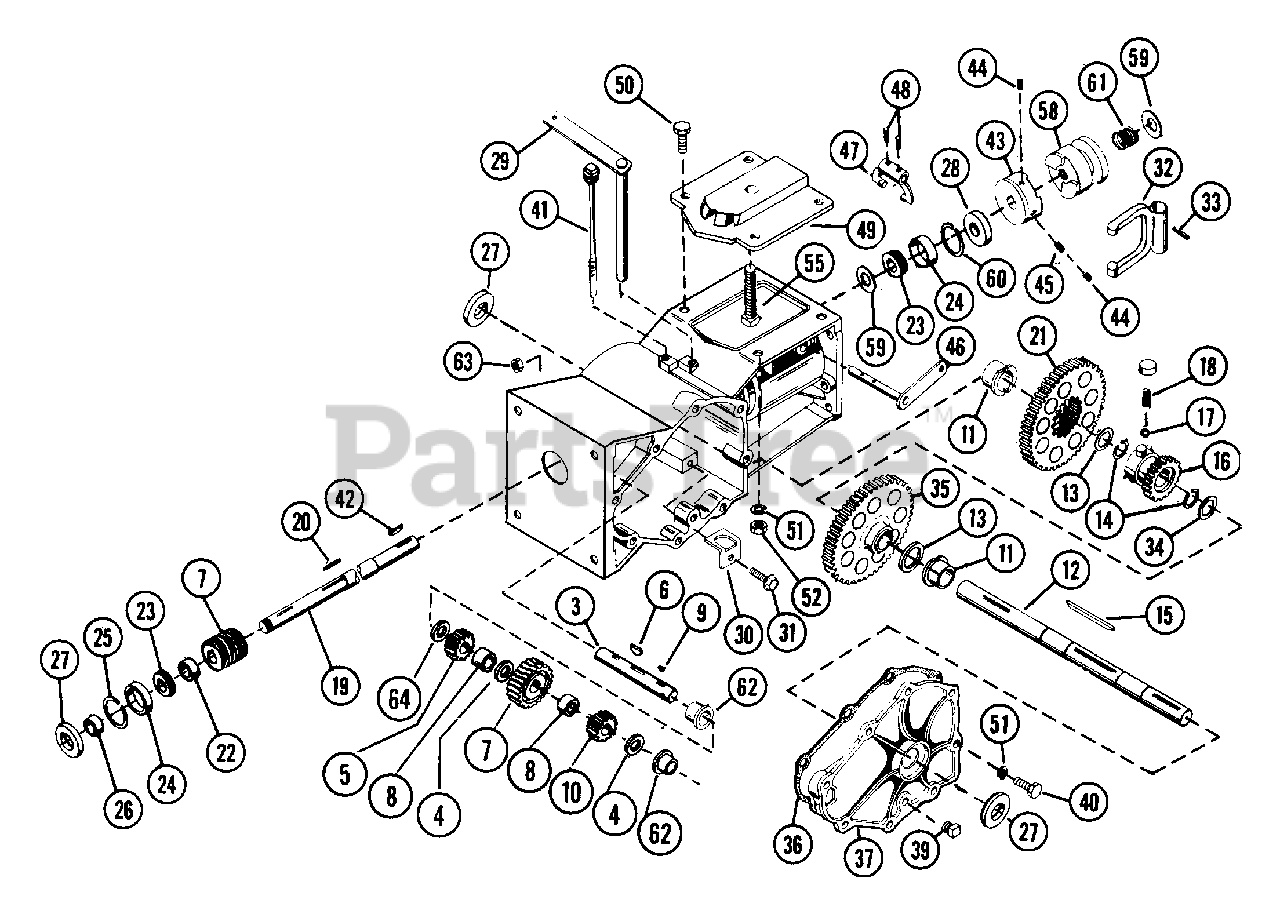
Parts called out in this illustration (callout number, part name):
1	TRANSMISSION GEARCASE
2	TRANSMISSION HOUSING
3	SHAFT, PINION
4	WSHR-HDND-THRST .758X1.23X.031
5	HIGH PINION
6	KEY-WDRF .25X.687X.375
7	WORM AND WORM GEAR
8	SPACER 1.25 X .75 X .75
9	KEY-FTHR .188X1.38X.188
10	LOW PINION
11	BSHG-FLG 1.000X1.25X1.000X1.50
12	AXLE SHAFT
13	WSHR-HRD-THRS 1.007X1.542X.062
14	RG-RTNG-EXT 1.00X.078
15	KEY-FTHR .25X2.75X.25 SAE1035
16	CLUTCH HUB
17	STEEL BALL
18	SG-COMP .047X.31X.593 WLD11
19	WORM SHAFT
20	KEY-SQ .188X1.0X.188 SAE 8630
21	HIGH GEAR
22	BSHG, SPCR .755X1.12X.50 PM
23	BRG-CONE .750X.61
24	BRG-CUP 1.781X.475
25	SNAP RING KIT
26	SPACER BUSHING .99 X .75 X .50
27	SEAL 1.000X1.785X.250
28	SEAL .750X1.781X.250
29	HIGH-LOW SHIFT LEVER
30	RETAINER CLIP
31	SCR-FLG-WHZ 10-24X.75 PL
32	SHIFT YOKE
33	PIN-ROLL .250X1.00
35	LOW GEAR
37	TRANSMISSION COVER
39	PIPE PLUG
40	BLT-HEX .31-18X1.00 PL GR 2
41	DIP STICK
42	KEY-FTHR .188X1.25X.187 SAE
43	TILLER DRIVING JAW
44	SCR-SET .32-18X.38 SKHCUPNL OH
45	SCR-SET .32-18X.50 SKHHOP OH
46	TINE ENGAGING FORK SHAFT
47	CLUTCH FORK
48	PIN-ROLL .188X1.00
49	PIVOT CAP
50	BLT-HEX .31-18X1.00 PL GR 2
51	WSHR-LK .312X.097 PL HVY
52	NUT-HEX .312-18
55	SWIVEL BOLT
58	TILLER JAW CLUTCH
59	WSHR-FL-STL .755X1.375X.125
60	RG-RTNG-INT 1.781X.052
61	SG-COMP .080X.97X2.18 WLD14
62	BSHG-FLG .750X1.000X.750X1.250
63	NUT-HEX .375-16
64	WSHR-HDND-THRST .760X1.25X.094
